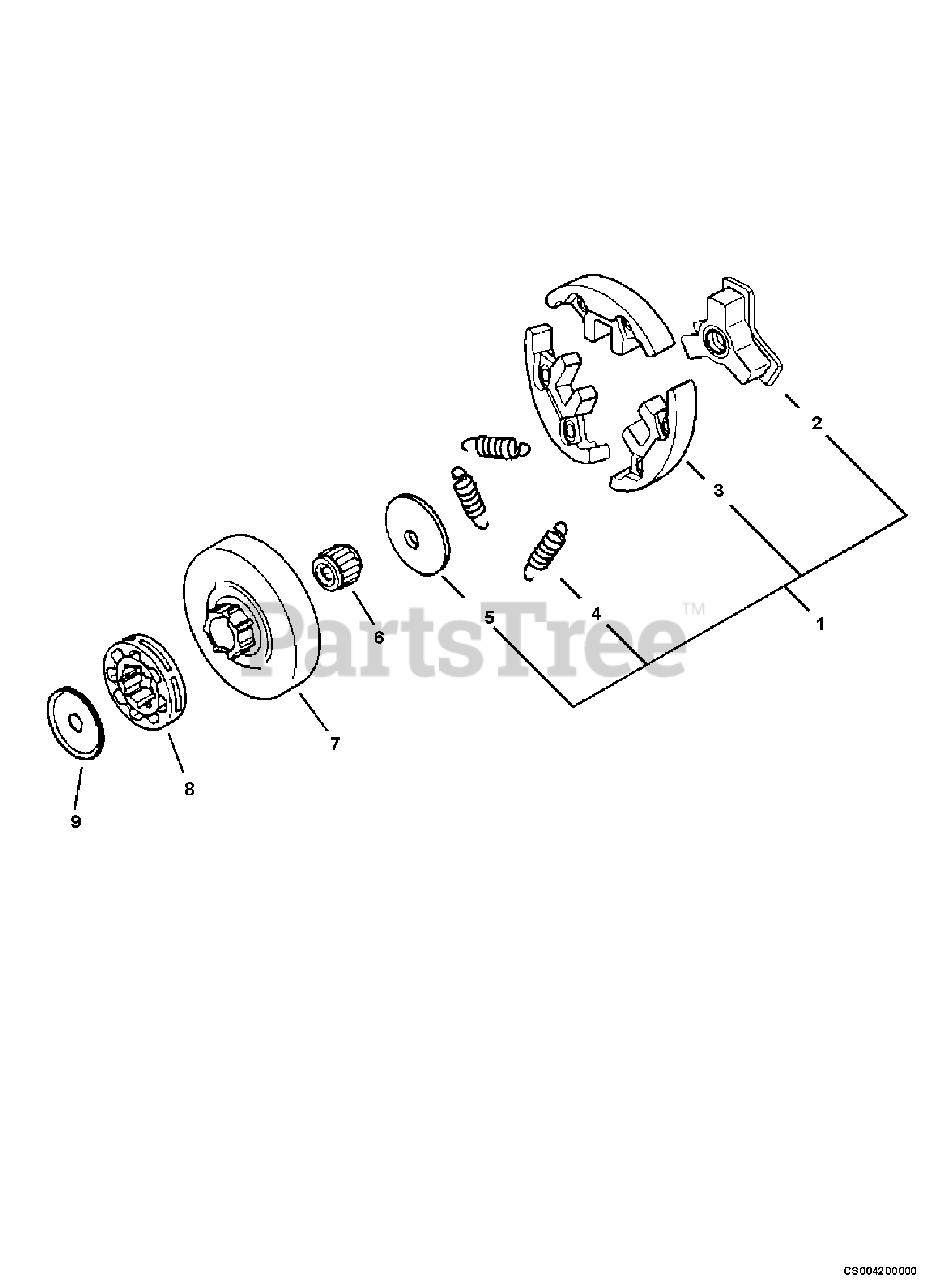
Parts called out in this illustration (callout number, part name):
1	CLUTCH ASSY
2	HUB, CLUTCH
3	CLUTCH SHOE SET
4	SPRING, CLUTCH
5	PLATE, CLUTCH
6	BEARING, NEEDLE
7	DRUM, CLUTCH
8	SPROCKET, RIM
9	PLATE, CLUTCH
